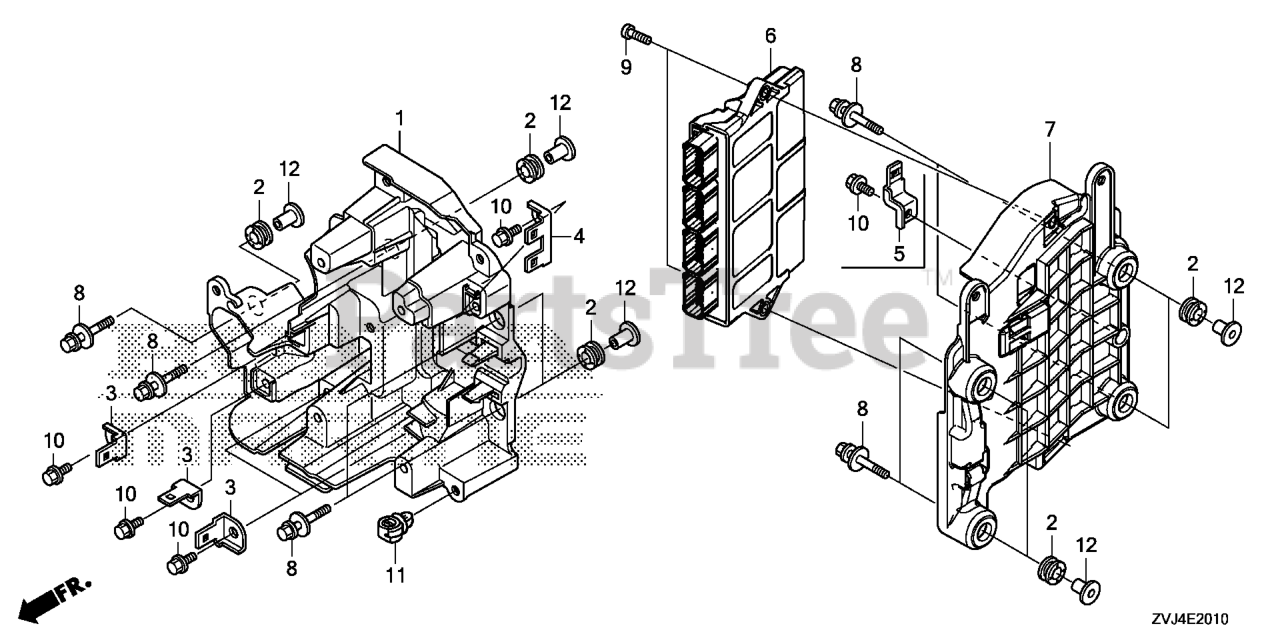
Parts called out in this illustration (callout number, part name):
1	CASE, ELECTRONIC PARTS
2	GROMMET, ELECTRONIC PARTS CASE
3	BRACKET, ALTERNATOR FUSE
4	BRACKET, CONNECTOR A
5	BRACKET, CONNECTOR (D)
6	ECU ASSY.
7	CASE, ELECTRONIC CONTROL UNIT
8	BOLT-WASHER (6X27)
9	BOLT, TORX (M6X20)
10	BOLT, FLANGE (6X10)
11	CLIP, WIRE HARNESS (25MM)
12	COLLAR, MODULE IGNITION CONTROL CASE (CDI)
12	COLLAR (12X6.5)
